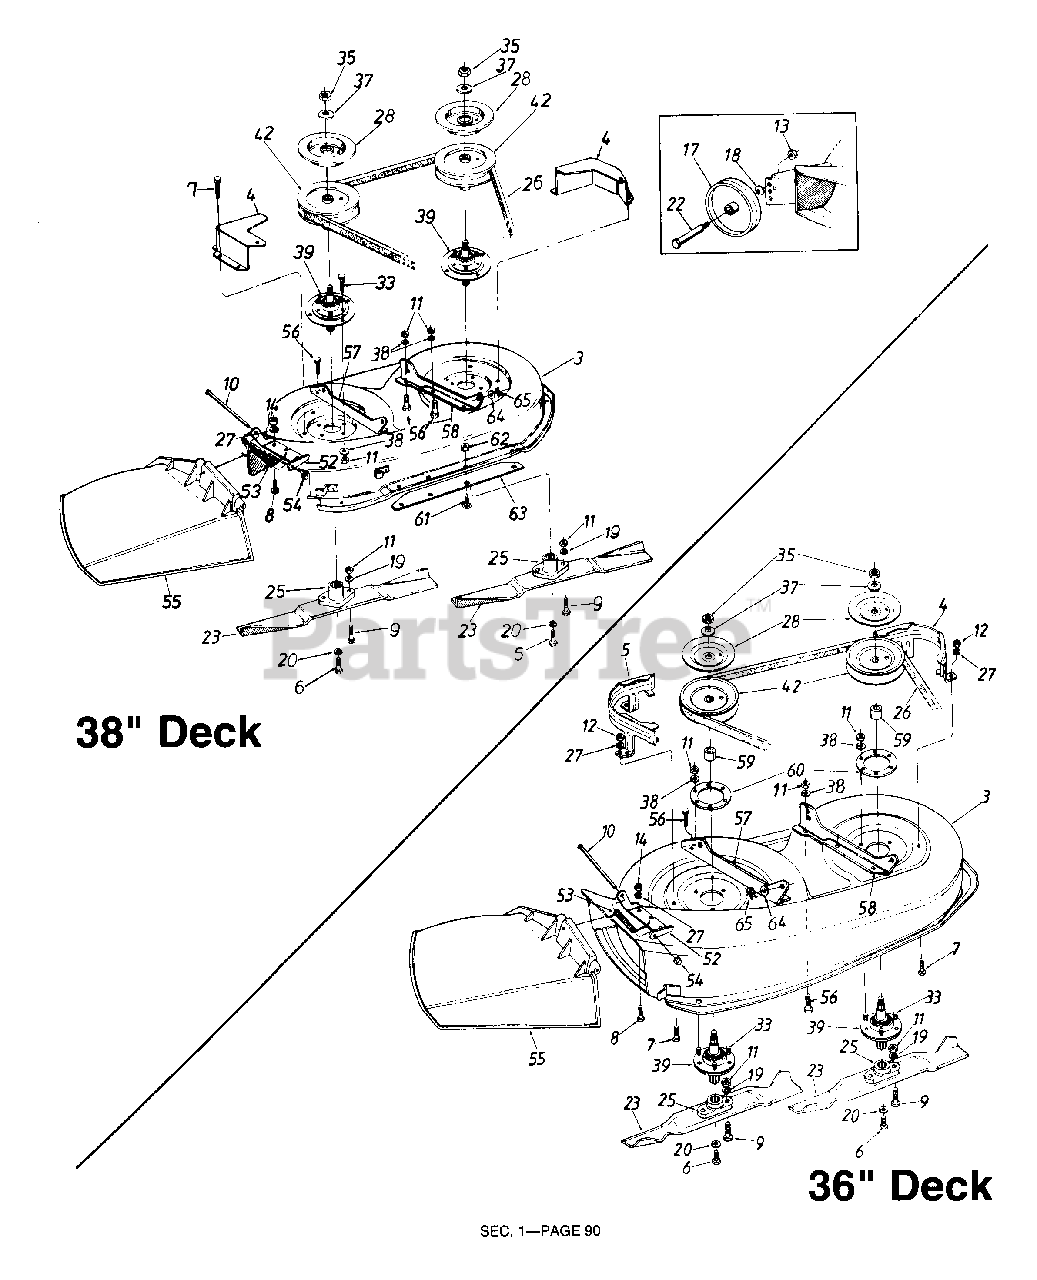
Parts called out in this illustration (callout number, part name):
3	36" Deck Ass'y.
7	Hex Bolt 1/4-28 x .62" Lg. (36" Deck)
8	Truss Mach. Scr. 1/4-20 x .75" (36" Deck)
9	Hex Bolt Special 5/16-24 x 1.0"
10	Hinge Pin
11	Hex Nut 5/16-24 Thd.
12	Hex Nut 1/4-28 Thd. (36" Deck)
13	Hex Top L-Nut 3/8-16 Thd.
14	Hex Nut 1/4-20 Thd.
17	Deck Wheel - 5"
18	Bell-Wash..40" I.D. x .88" O.D.
19	L-Wash. 5/16" I.D.
20	L-Wash. 3/8" I.D.- H.D.
22	Shld. Bolt .498" Dia. x 1.53"
23	High-Lift Blade (36" Deck)
25	Blade Adapter
26	"V"-Belt (36" Deck)
27	Bell-Wash. 1/4" I.D.
28	Brake Disc
33	Rib Neck Bolt 5/16-24 x .84" Lg. (36" Deck)
35	Hex Jam Nut 5/8-18 Thd.
37	L-Wash. 5/8" I.D.
38	Bell-Wash..345" I.D. x .88" O.D.
39	Blade Spindle Ass'y. Comp.
42	5" Dia. Pulley
52	Hinge Mtg. Brkt.
53	Torsion Spring
54	Push Nut
55	Chute Ass'y. Comp.
56	Hex Bolt 5/16-24 x .75" Lg.
61	Carr. Bolt 1/4-20 x .5" Lg. (38" Deck)
62	Hex Sems Nut 1/4-20 Thd.(38" Deck)
65	Hairpin Clip 3/8" Dia.
